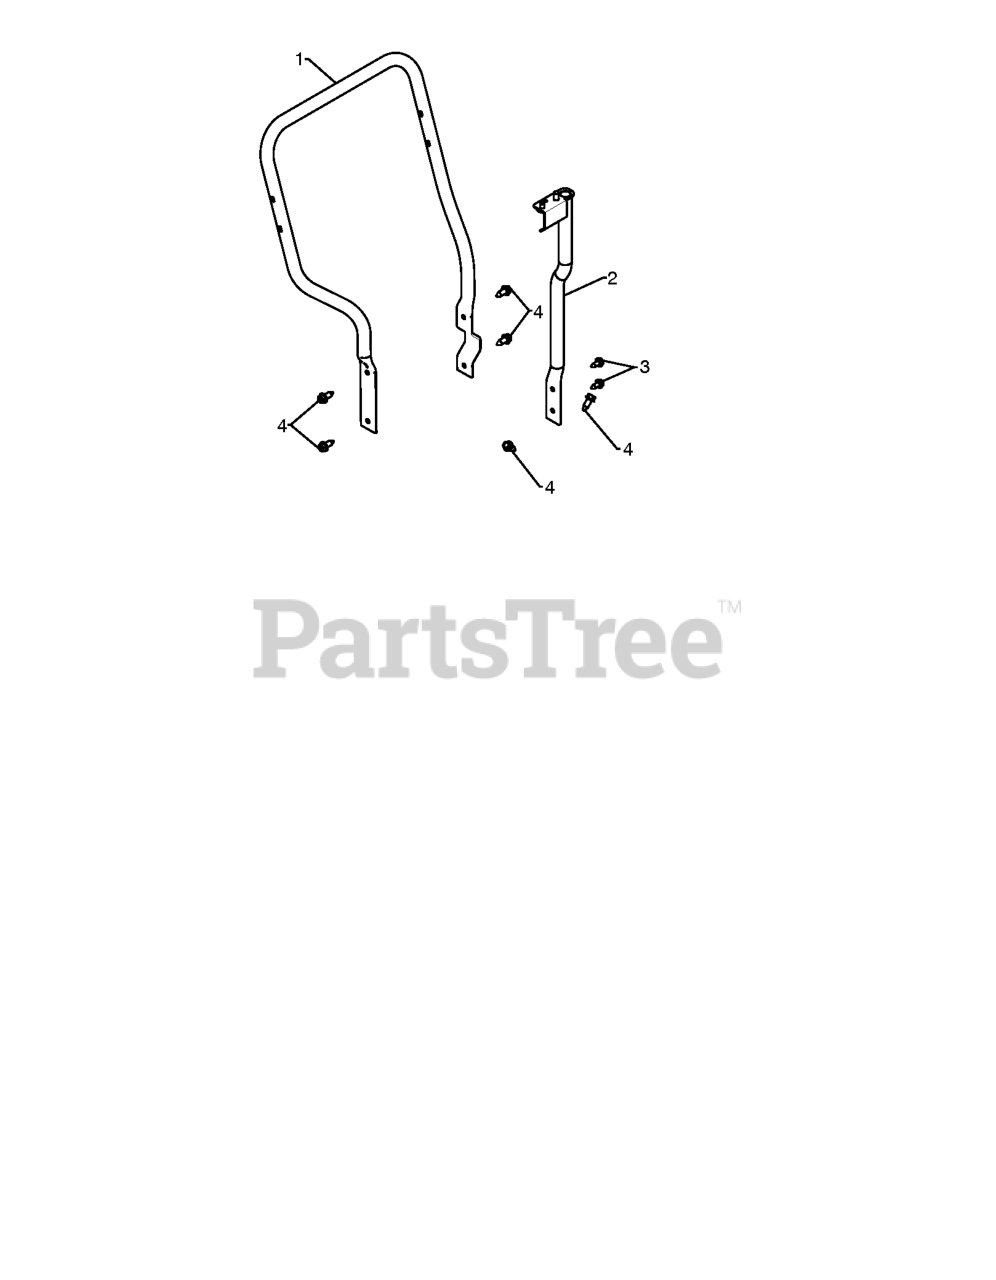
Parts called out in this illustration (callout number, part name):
1	TUBE.LOWER.HANDLE.SNOW.GRAY
2	SUPPORT.WELDMENT.ROTATOR.
3	BOLT.HEX.HD.WASHER.5/16-18X.75
4	SCREW 3/8-16X1
